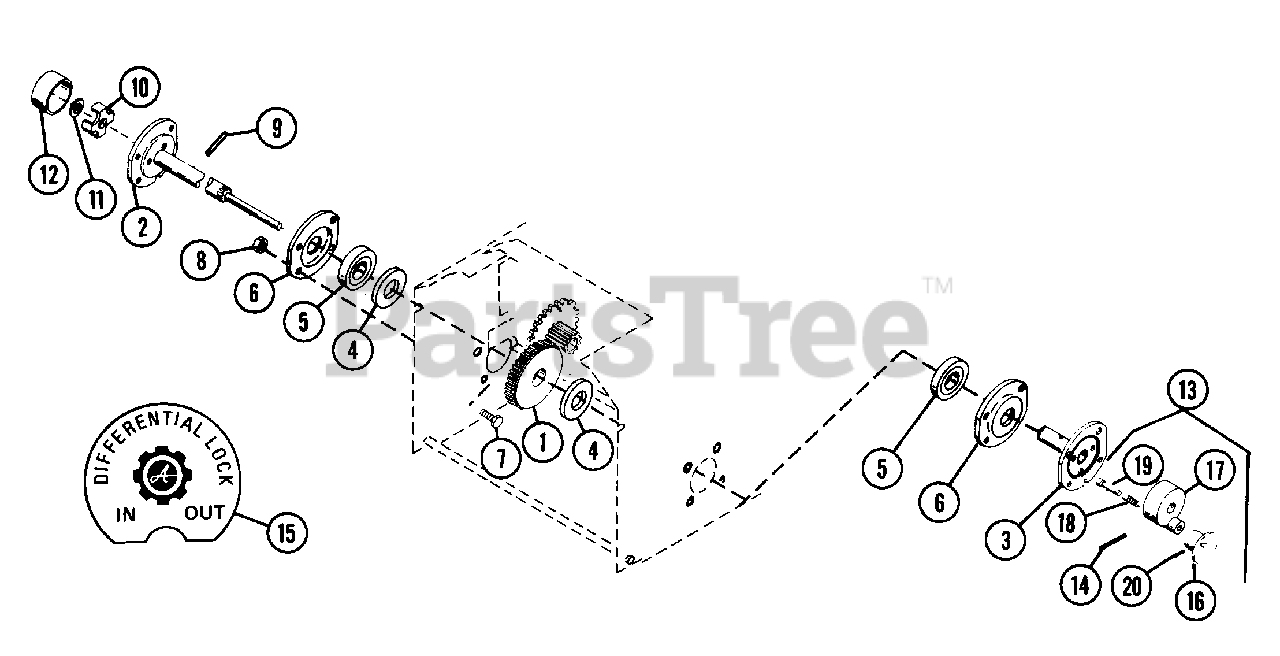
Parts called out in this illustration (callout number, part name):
1	DIFFERENTIAL ASSEMBLY
2	R H AXLE
3	L H AXLE ASSEMBLY
4	WSHR-FL-STL 1.140X1.718X.134
5	BRG-BALL 1.13X2.18X.63
6	BEARING RETAINER
7	SCR-SLTR-SERNK .25-20X.62 PL
8	NUT-LK-FLG .250-20 PL
9	PIN-ROLL .188X1.50
10	SPINDLE CUP
11	PUSHNUT
12	HUB CAP
13	HUB, LOCKOUT
14	PIN-GRV .250X1.75 TP C
15	DIFFERENTIAL LOCK LABEL
17	LOCKOUT HUB
18	SG-COMP .028X.34X1.062 WLD75
20	PIN-ROLL .093X1.00
